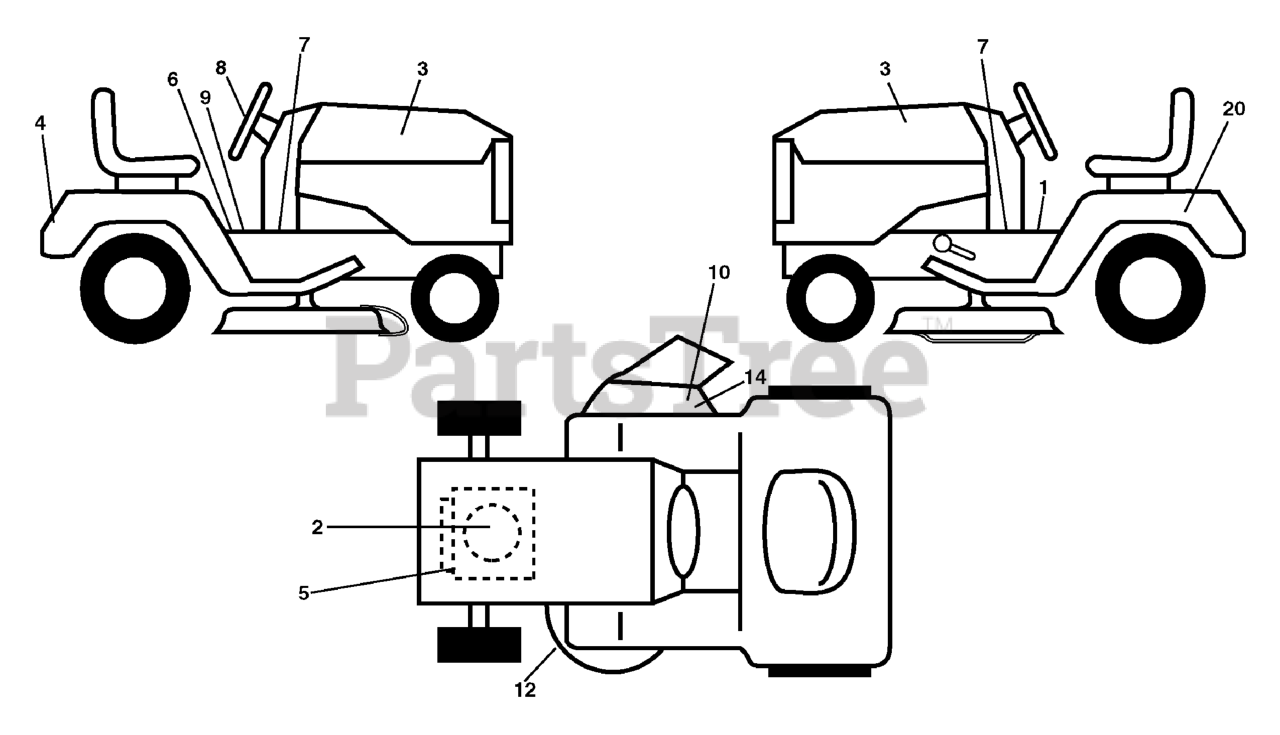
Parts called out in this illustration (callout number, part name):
1	DECAL, Warning Symbols
2	DECAL, Engine HP
3	DECAL, Hood LH/RH
4	DECAL, Fender
5	DECAL, Warning Eng. Symbols
6	DECAL, Brake Clutch
7	DECAL, Lower Dash
8	DECAL, Steering
9	DECAL, Saddle Brake Park
10	DECAL, Cutfinger CE
12	DECAL, V-Belt Drive Schematic
14	DECAL, Safety Warning
20	DECAL, Battery Dngr/Psn Eng
